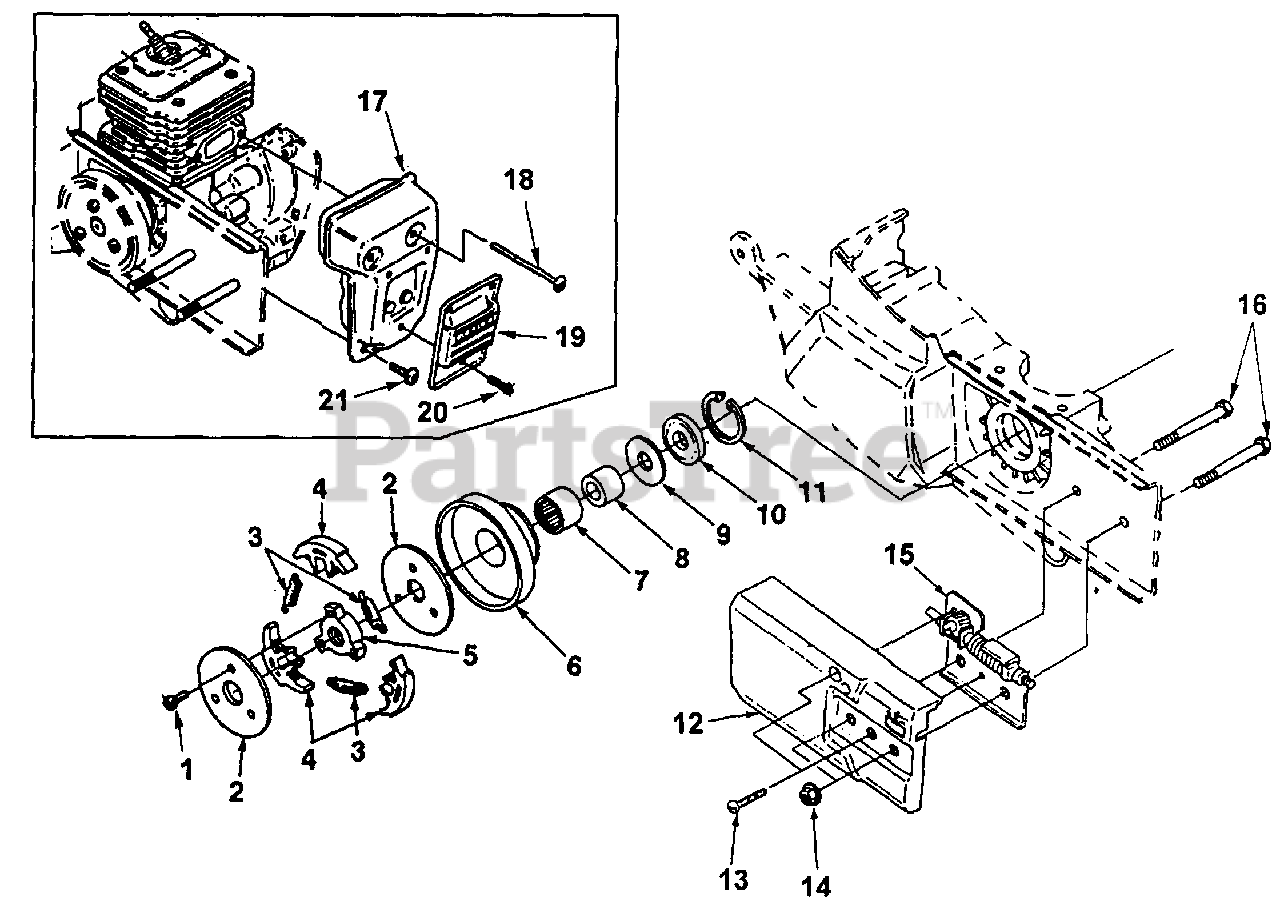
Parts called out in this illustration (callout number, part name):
1	SCREW-Machine Hex Hd. (8-32 X 3/8")
2	COVER-Clutch
3	SPRING-Clutch
4	SHOE-Clutch
5	CLUTCH-Spider
6	PULLEY-Drum & Bearing
7	BEARING-Needle
8	RACE-Inner
9	WASHER-Thrust
10	SEAL-Main
11	RETAINER-Bearing
12	CLUTCH-Cover
13	SCREW-Taptite (8-32 x 5/8")
14	NUT-Hex Flange (5/16-18)
15	GEAR KIT
16	BOLT-Wheel Arm
17	MUFFLER
18	SCREW-Truss Hd. (10-24 x 2 1/2")
19	CAP-Muffler
20	SCREW-Machine Hex Hd. (8-32 x 1/2")
21	SCREW-Torx (10-24 x 1/2")
